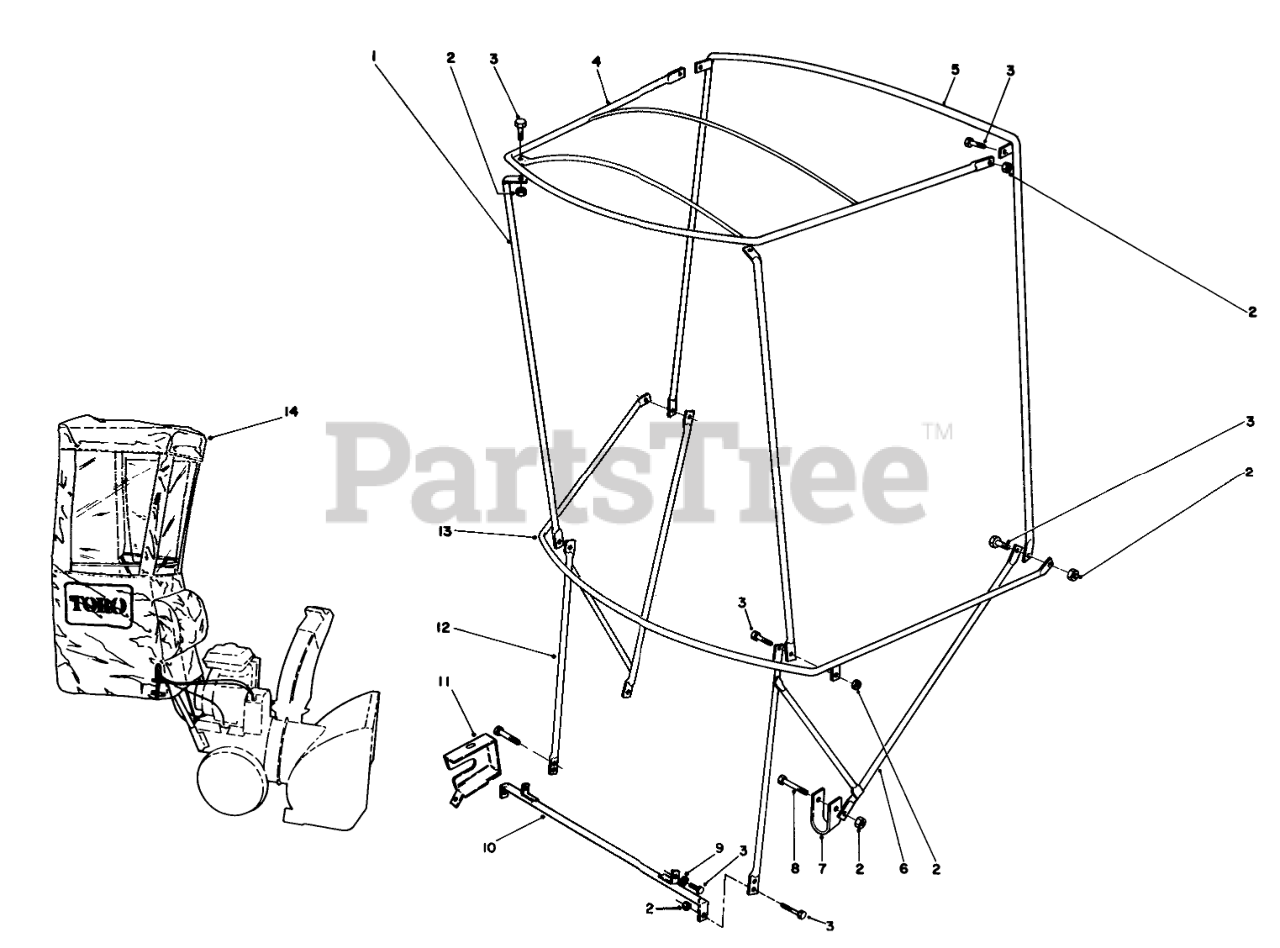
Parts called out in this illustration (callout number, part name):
2	NUT-HEX, SIDE DEFORM
3	SCREW-HH
4	FRAME-TOP
5	BOW-VERTICAL, REAR
6	Bracket-LH
7	CLAMP
8	SCREW-HH
9	WASHER-FLAT
10	Bracket-Base
11	COVER-LOCK, LEVER
12	BRACKET-RH
13	BOW-CURVED
14	Cover-Vinyl
